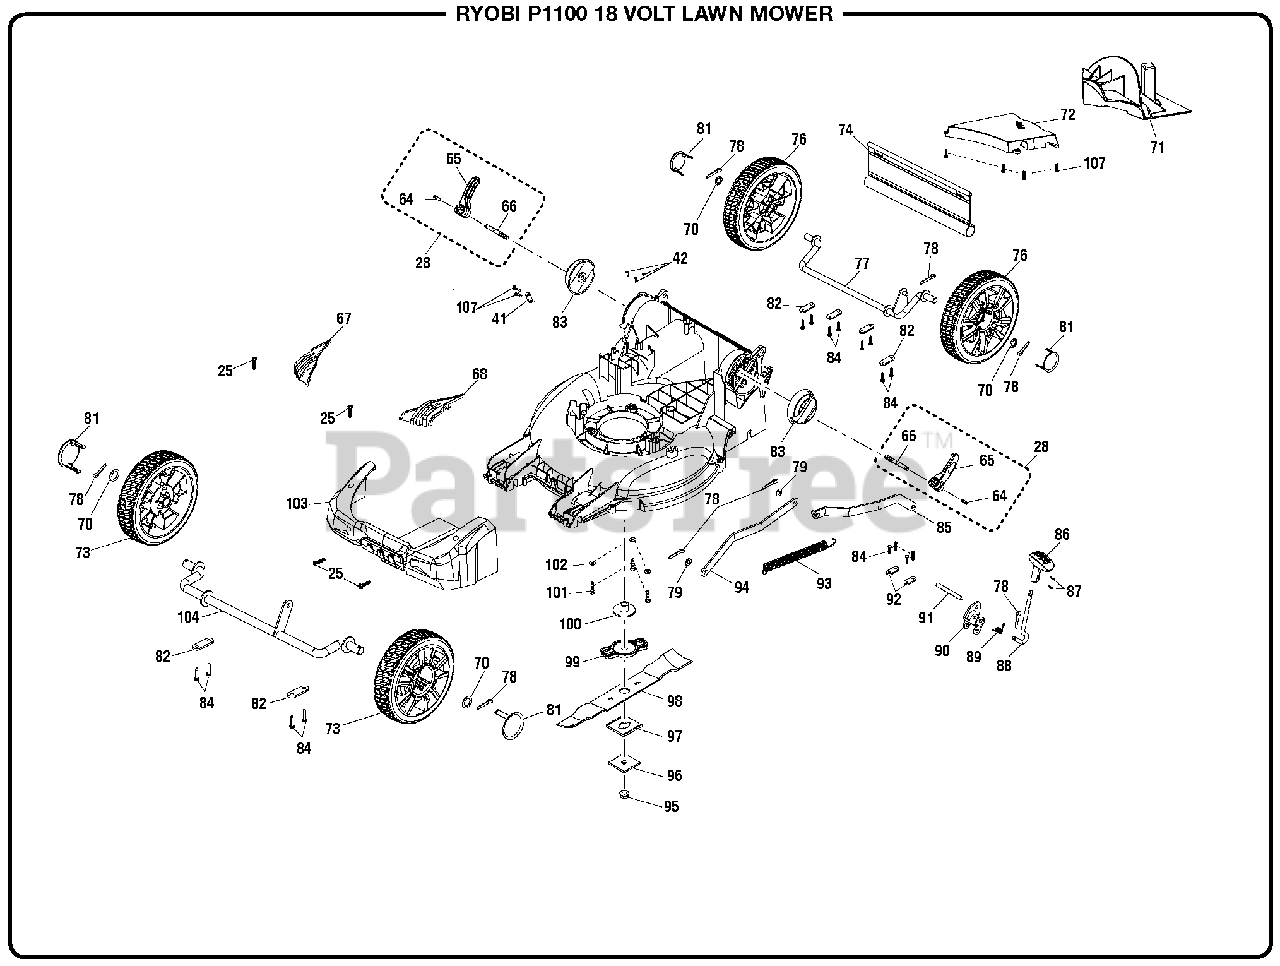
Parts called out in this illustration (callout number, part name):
25	Screw (M3.5 x 20 mm, T20 Torx Pan Hd.)
28	Handle Lock Assembly
41	Cord Clip
42	Screw (M4.2 x 12 mm, T20 Torx Pan Hd.)
64	Spring Pin
66	Quick Lock Press
67	Grass Protector (Right)
68	Grass Protector (Left)
70	Washer (OD20 x ID13 x 1t)
71	Mulching Plug
72	Rear Cover
73	Front Wheel w/Bearing & Cap 6 in.
74	Rear Skirt
76	Rear Wheel w/Bearing & Cap 8 in.
77	Rear Wheel Axle
78	Cotter Pin (2.5)
79	Washer (OD18 x ID8.4 x 1t)
81	Wheel Cover
82	Axle Pressure Plate
83	Base (Lock Handle)
84	Screw (M4 x 18 mm, Torx Pan Hd.)
85	Rear Lift Rod
86	Height Adjustment Handle
87	Screw (M3 x 9 mm, Flat Hd.)
88	Height Adjustment Lever
89	Torsion Spring (Height Adjustment)
90	Height Adjustment Bracket
91	Axle (Height Adjustment)
92	Pressure Plate (Height Adjustment)
93	Retention Spring
94	Front Lift Rod
95	Blade Nut (M10)
96	Blade Retainer
99	Blade Holder
100	Motor Shaft Bushing
101	Bolt (M6 x 16 mm, Hex Hd.)
102	Washer (OD15 x ID6 x 1t)
104	Front Wheel Axle
107	Screw (M4 x 16 mm, T20 Torx Pan Hd.)
